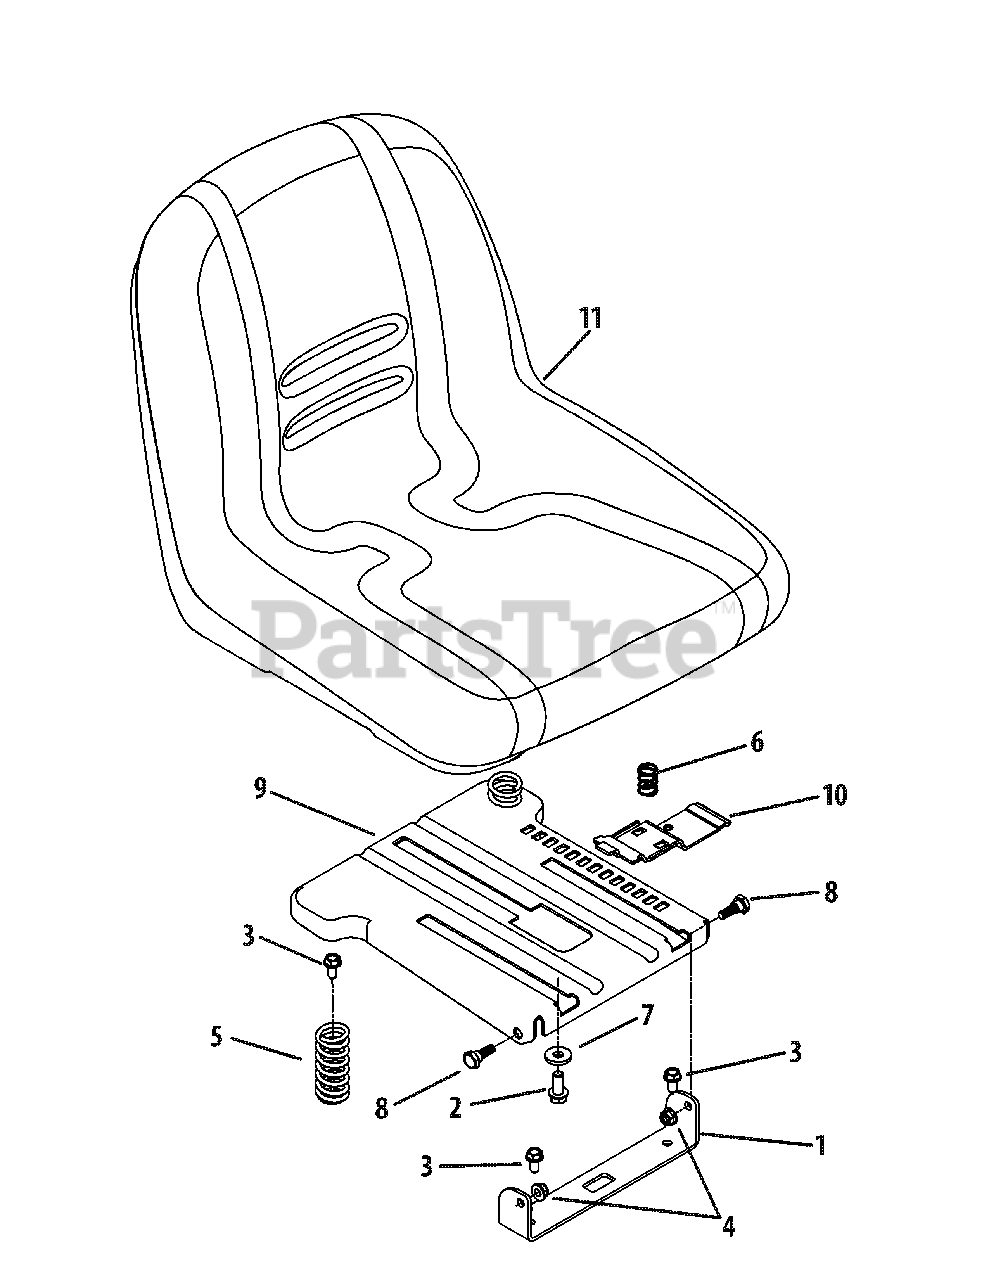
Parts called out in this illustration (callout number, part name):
2	Hex Flange Bolt, 3/8-16 x .875
3	Hex Washer Screw, 5/16-18 x .750
4	Flange Lock Nut, 5/16-18
5	Compression Spring
6	Compression Spring
7	Flat Washer, .385 x 1.0 x .135
8	Shoulder Screw, 5/16-18 x .437 x .268
9	Seat Mount Bracket
10	Seat Adjustment Lever
11	High Back Seat
